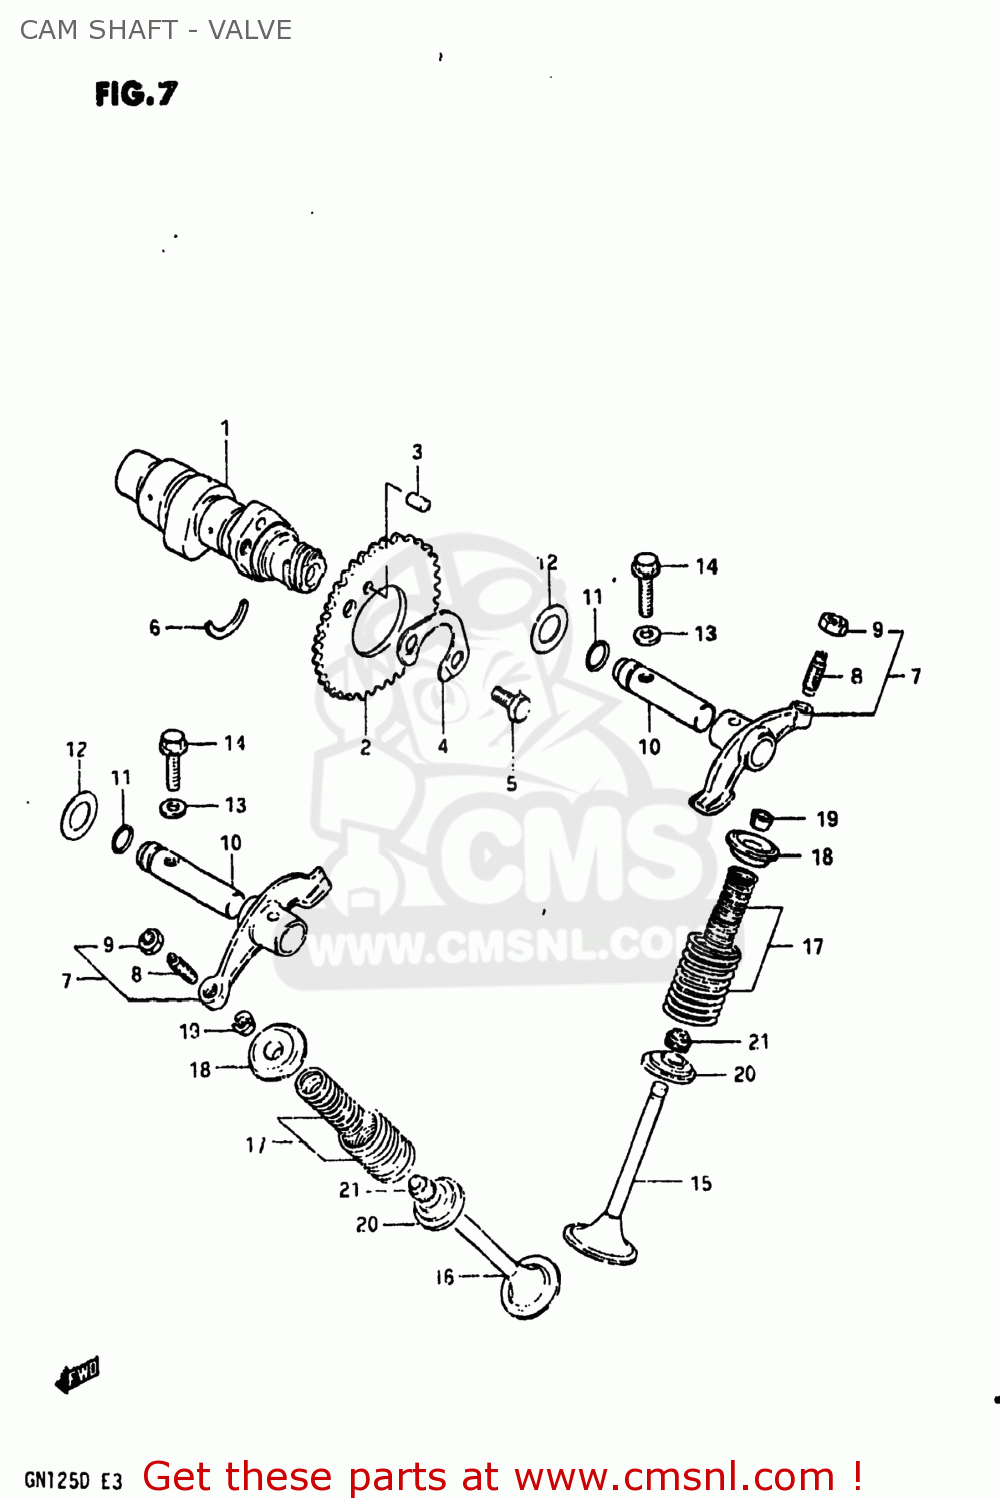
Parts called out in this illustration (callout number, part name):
1	CAMSHAFT
2	SPROCKET,CAMSHAFT
3	PIN(5X8)
4	WASHER,SPROCKET
5	BOLT(6X10.5)
6	C RING
7	ARM,VALVE ROCKER
8	SCREW,TAPPET ADJUSTING
9	NUT,ADJUSTING SCREW
10	SHAFT,VALVE ROCKER
11	O-RING
12	WASHER
14	BOLT
15	VALVE,INTAKE
16	VALVE,EXHAUST
17	SPRING SET,VALVE
18	RETAINER,VALVE SPRING
19	COTTER VALVE
20	SEAT,VALVE SPRING
21	OIL SEAL
